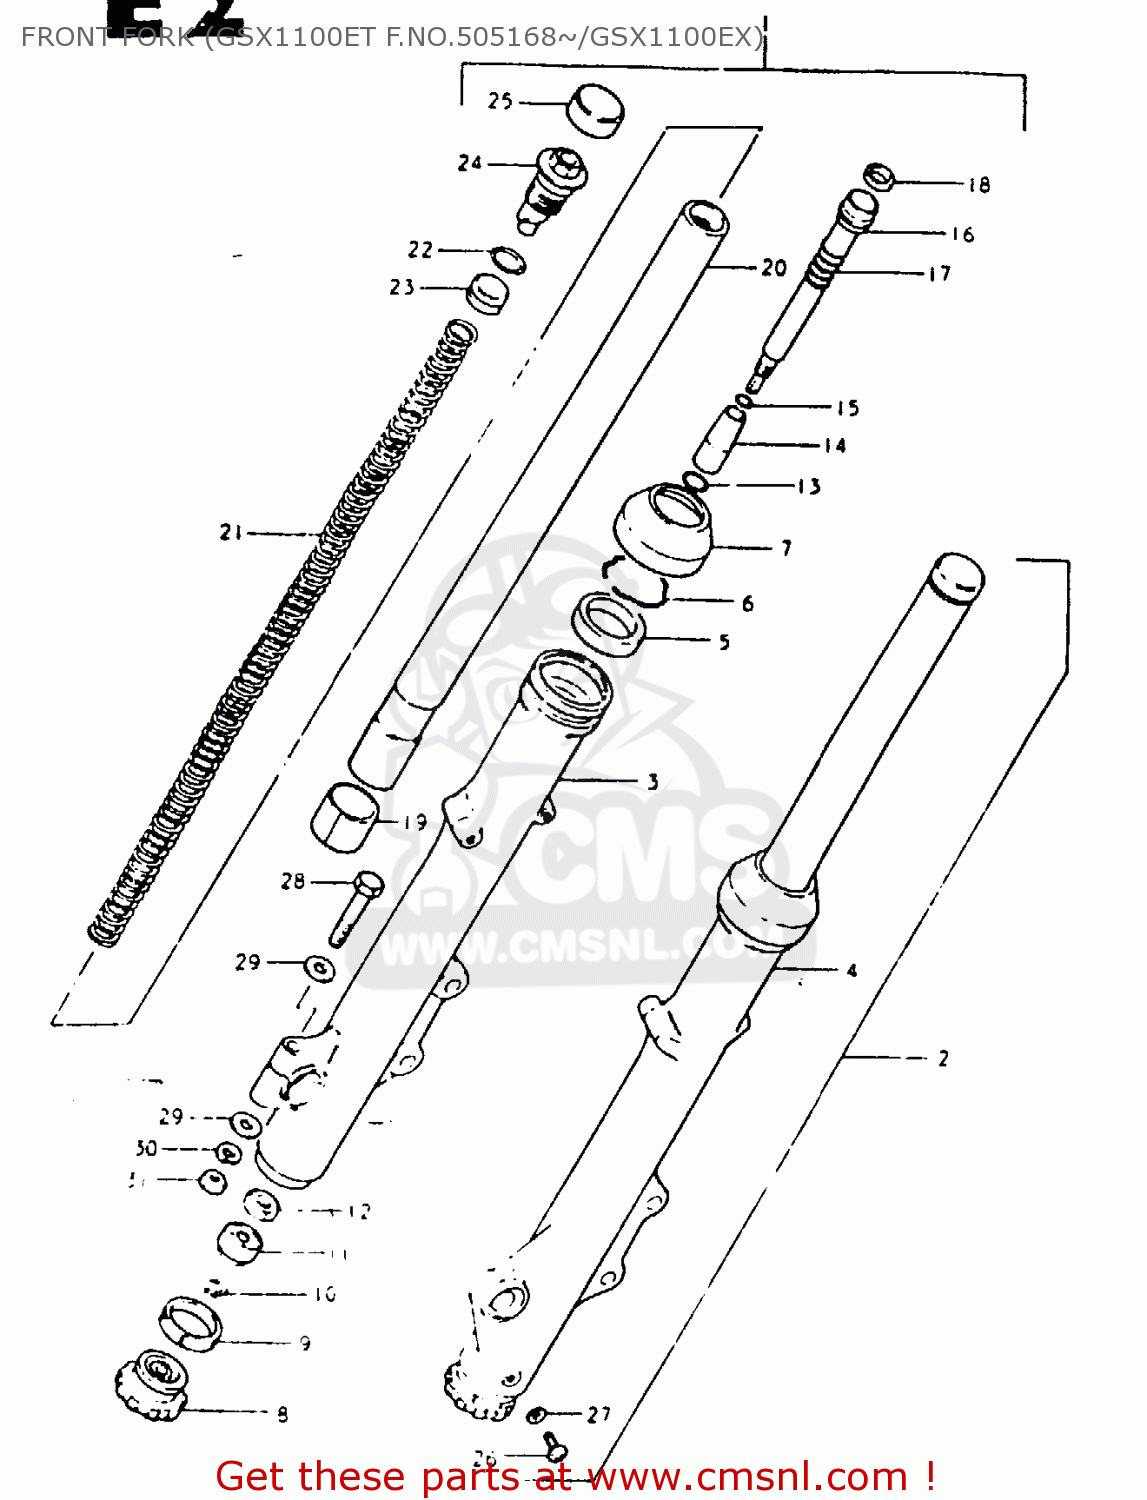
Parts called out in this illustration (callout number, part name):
1	DAMPER ASSY, RH
2	DAMPER ASSY, LH
3	OUTER TUBE, RH
4	OUTER TUBE, LH
5	OIL SEAL,FRONT FORK
6	RING,STOPPER
7	SEAL,DUST
8	HANDLE
9	RING
10	CIRCLIP
11	DETENT
12	NUT
13	O RING
14	PIECE, OIL LOCK
15	O RING
16	CYLINDER
17	SPRING,FORK REBOUND
18	RING,PISTON
19	PISTON
20	INNER TUBE
21	SPRING
22	O-RING
23	PISTON,FREE
24	CAP
25	CAP
26	SCREW
27	GASKET,DRAIN,PLUG (NAS)
28	BOLT 8X50
29	WASHER
30	WASHER,LOCK,8.
31	NUT
